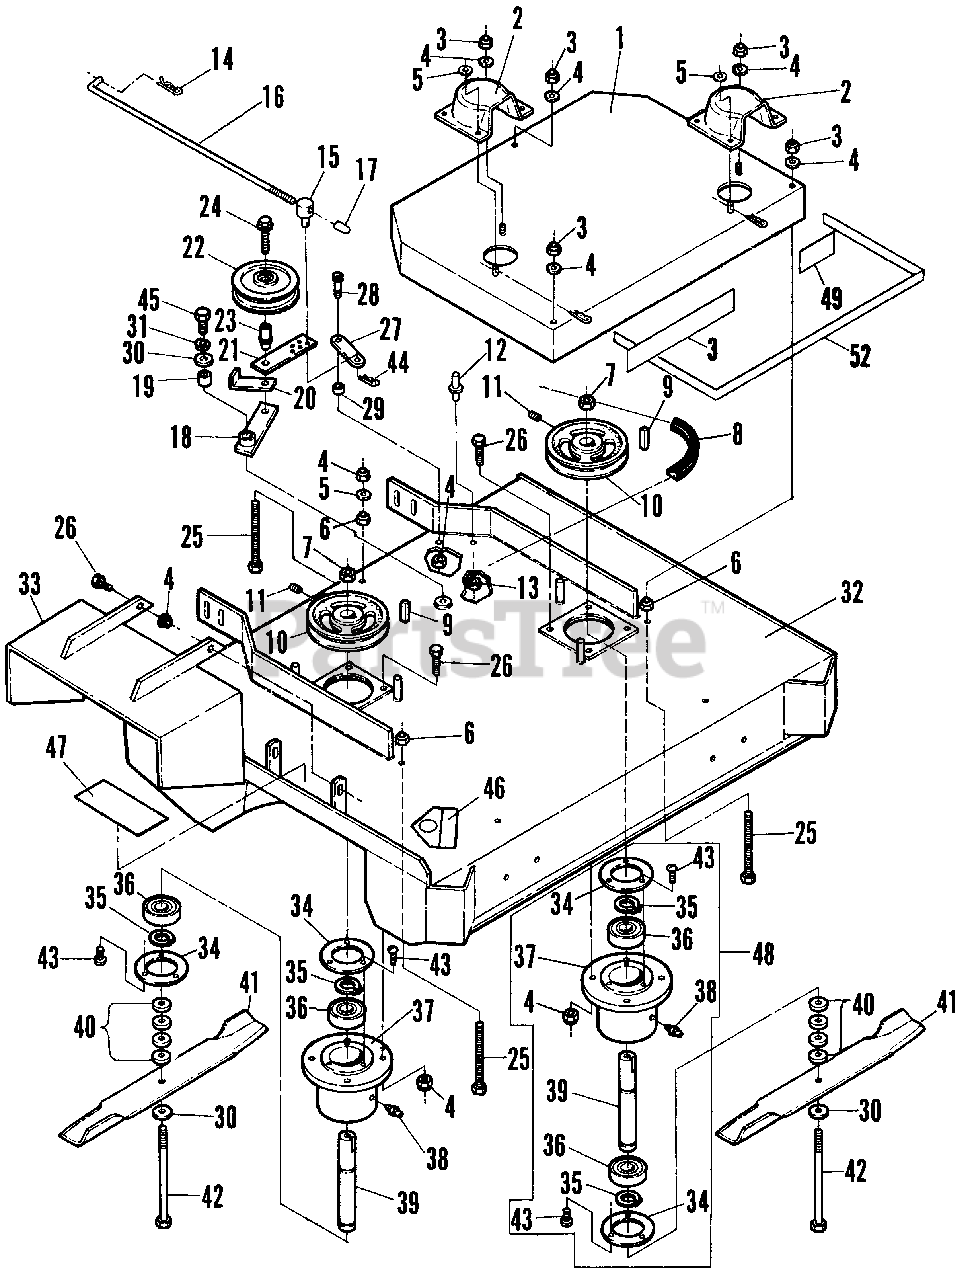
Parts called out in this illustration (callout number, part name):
1	BELT COVER W/DECALS
2	COVER, Spindle
3	DECAL, "SNAPPER"
4	NUT, 5/16-18 Nyloc Hex
5	WASHER, 5/16 Std. Flat
6	NUT, 5/16" - 18 Whizlock
7	NUT, 5/8-18 Hex
8	BELT, Engine/Blade
9	KEY, 1/4 Square x 1 1/4
10	PULLEY, W/Set Screws
11	SCREW, Set
12	STUD, Stop
13	NUT, 3/8-16 Whizlock
14	COTTER, #2 Hairpin
15	SWIVEL
16	ROD, Blade Drive
18	ARM, Idler w/Bushing
19	BUSHING
20	SNUBBER, Belt
21	ARM, Tightening
22	PULLEY, Idler
23	BUSHING, Flange
24	BOLT, Flange Lock 3/8-16 x 1 3/4
25	SCREW, Hex Head Cap 5/16-18 x 3 1/4
26	SCREW, Hex Head Cap 5/16-18 x 1 GR.5
27	ARM, Blade Assist
28	BOLT, Knurled Socket Head Shoulder 3/8 x 3/4
30	WASHER, Flat 5/8
31	WASHER, Lock 5/8
32	DECK, Front 32 w/Decals
33	DEFLECTOR, Chute
34	CAP, CUTTER HOUSING
35	RING, RETAINING
36	BEARING (SINGLE SEAL)
37	HOUSING, CUTTER
38	ZERK, 1/8 NPT
39	SPINDLE, CUTTER
40	SPACER, Blade
41	BLADE 16 1/4 HIGH LIFT (.204)
42	SCREW, Hex Head Cap 5/8-18x7 1/2
43	SCREW, SELF-TAPPING 10 - 24 x 1/2
44	COTTER, Hairpin #4
45	SCREW, Hex Head Cap 5/8-11 x 1
46	DECAL, CPSC
47	DECAL, "Caution"
48	ASSEMBLY, CUTTER HOUSING
49	DECAL, 32 Inch
52	DECAL STRIPE
